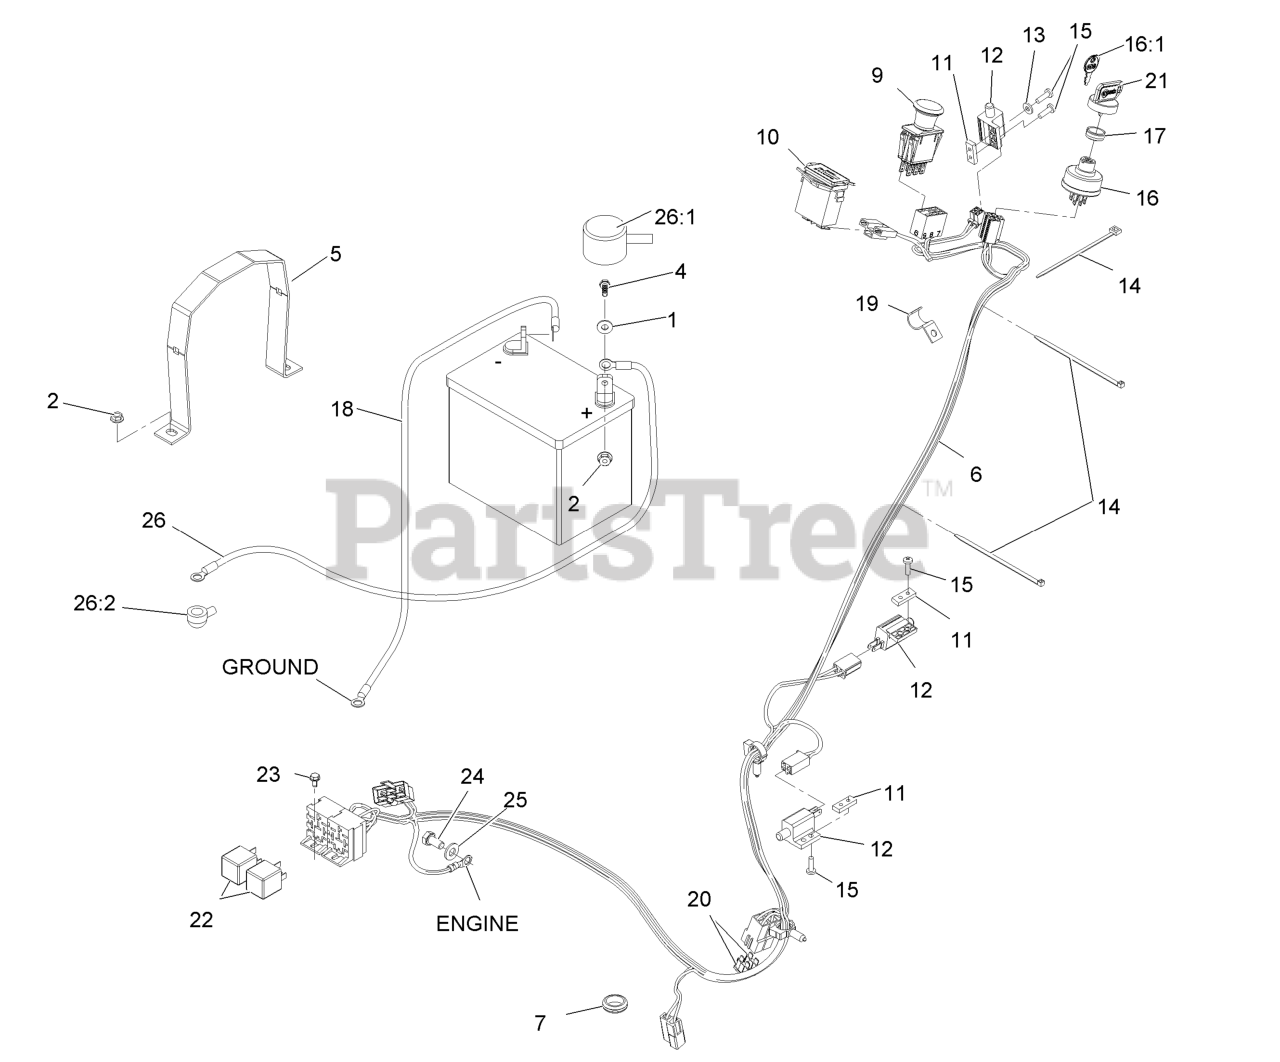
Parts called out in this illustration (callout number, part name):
1	WASHER-FLAT
4	SCREW-HH
5	STRAP,BATTERY HOLDDOWN
7	GROMMET
9	SWITCH-PTO
10	METER-HOUR
11	PLATE-TAPPED
12	SWITCH-OPEN, NORMALLY
13	WASHER-FLAT
14	TIE-PLASTIC
15	SCREW-PPH
16:1	KEYS-IGNITION (SPARE PAIR
17	NUT-SWITCH, IGNITION
18	WIRE-GROUND
19	CLIP-HALF, LOOM
20	FUSE-BLADE TYPE, 20 AMP
21	KEY-IGNITION
23	SCREW-HWH
24	SCREW-HH
25	WASHER-PLAIN
26	POSITIVE BATTERY CABLE AS
26:1	INSULATOR-BATTERY
26:2	INSULATOR-SOLENOID
